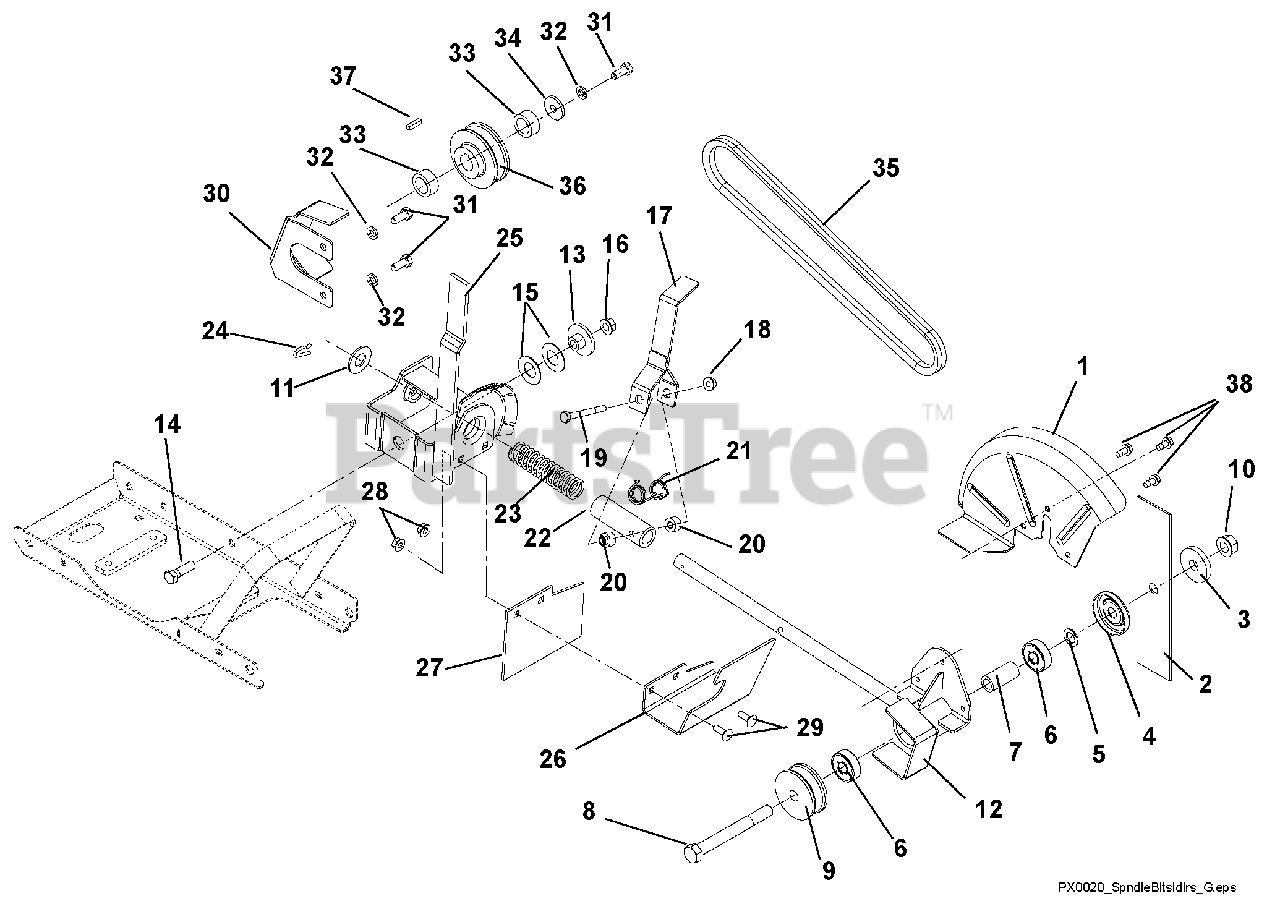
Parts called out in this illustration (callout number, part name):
1	Guard, Blade
2	Blade, Edger - 9"
3	Washer, Flat Steel .515 x 1.625 x .250
4	Slinger, Bearing
5	Washer, Flat Steel .52 x .827 x .062
6	Bearing, Ball .50 x 1.38 x .437
7	Bushing, Sleeve .500 x .750 x 1.560
8	Bolt, Hex .50-13 x 4.50 Grade 5
9	Pulley, Blade
10	Nut, Locking Top Flange .50-13
11	Washer, Flat Steel .656 x 1.31 x .095
12	Spindle, Cutter Head
13	Flange Bushing Pivot
14	Bolt, Hex .38-16 x 1.25
15	Washer, Belleville
16	Nut, Locking Top Flange .38-16
17	Lever, Tilt
18	Nut, Locking Top Flange .25-20
19	Bolt, Hex .25-20 x 2.50 Grade 5
20	Bushing, Lever
21	Spring, Torsion
22	Collar, Spring
23	Spring, Compression
24	Pin, Spring Clip
25	Mount, Cutter Head, Pivot
27	Flap, Rubber
28	Nut, Locking Top Flange .25-20
29	Bolt, Round Head Short Square Neck .25-20 x .75 Grade 5
30	Belt Finger, Engine
31	Bolt, Hex .31-24 x .75 Grade 5
32	Washer, Lock .312 x .097
33	Bushing, Sleave .766 x 1.125 x .500
34	Washer, Flat Steel .344 x 1.125 x .500
36	Pulley, Engine
37	Key, Square .188 x .75 x .188
38	Screw, Tapping .25-20 x .50
